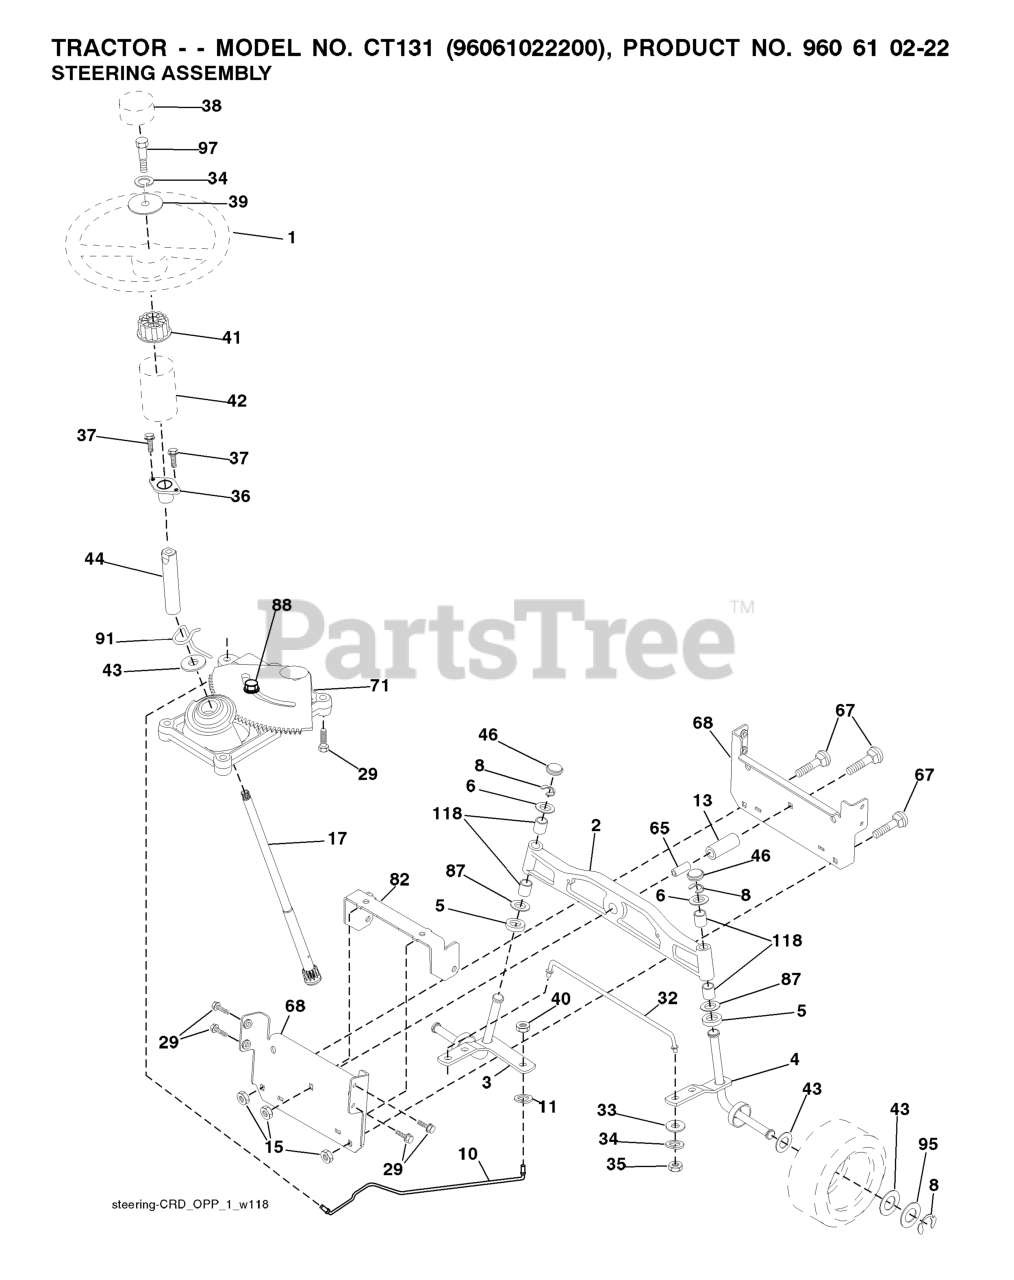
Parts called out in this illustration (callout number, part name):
1	WHEEL.STEERING.OPP.BLACK
2	AXLE ASSY FRONT
3	SPINDLE.ASM.LH.15"TIRES
4	SPINDLE.ASM.RH.15"TIRES
5	THRUST WASHER
10	DRAGLINK.15".TIRES.2001
11	WASHER, LOCK 3/8
13	TUBE, PIVOT AXLE
15	NUT
17	SHAFT STEERING SPLINE
29	SCREW, 3/8-16X3/4
32	ROD.ASM.TIE.BALL.JOINT.NOVAN
33	WASHER M
34	WASHER.LOCK.HVY.HLCL.SPR.5/16
35	NUT, CROWNLOCK
36	BUSHING, STEERING
37	SCREW.TT.#10-32X.5.3/8.FLANGE
38	CAP.WHEEL.STEER.OPP.BLK
39	WASHER.11/32
40	NUT CROWNLOCK 3/8-24
41	ADAPTER, WHEEL STNG..
42	BOOT.STEERING.SHAFT.BLACK
44	SHAFT.EXTEN.STRG.SPLINE
46	CAP.SPINDLE.BLACK
65	SPACER BRACE AXLE
67	BOLT CARRIAGE
68	BRACE.AXLE.15"TIRES
71	STEERING ASM
82	BRACKET.SUSP.CHASSIS.FRONT.15
87	WASHER, FLAT .781 X 1 1/2"
88	BOLT, SHOULDER 7/16-20
91	CLIP.STEERING
95	WASHER.HARDENED
118	BUSHING, AXLE CAST
